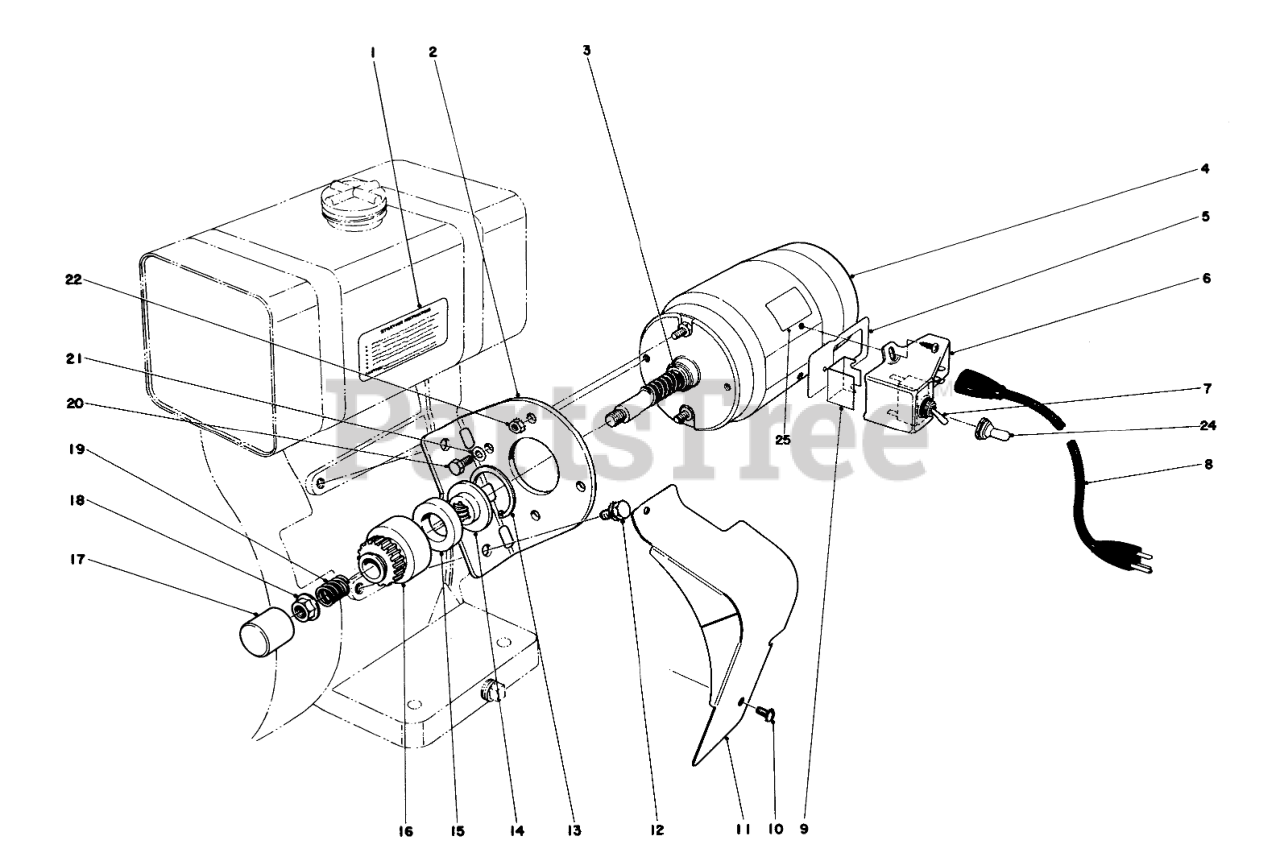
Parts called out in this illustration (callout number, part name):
1	Instruction Decal
2	Mounting Bracket
3	Spacer
4	Starter Motor
5	GASKET
6	Switch & Plug Housing
7	SWITCH & BOOT ASM
9	SWITCH INSULATOR
10	Hex Hd. Sems Screw
11	Pinion Shield
12	Screw-HH
13	Retaining Clip
14	Pinion Nut
15	RUBBER RING
16	PINION 16 TOOTH
17	WEATHER CAP
18	NUT-HHF
19	COMPRESSION SPRING
20	SLOT HD SCREW
21	WASHER-LOCK, INT
22	NUT-KEPS
24	BOOT-SWITCH
25	Decal
